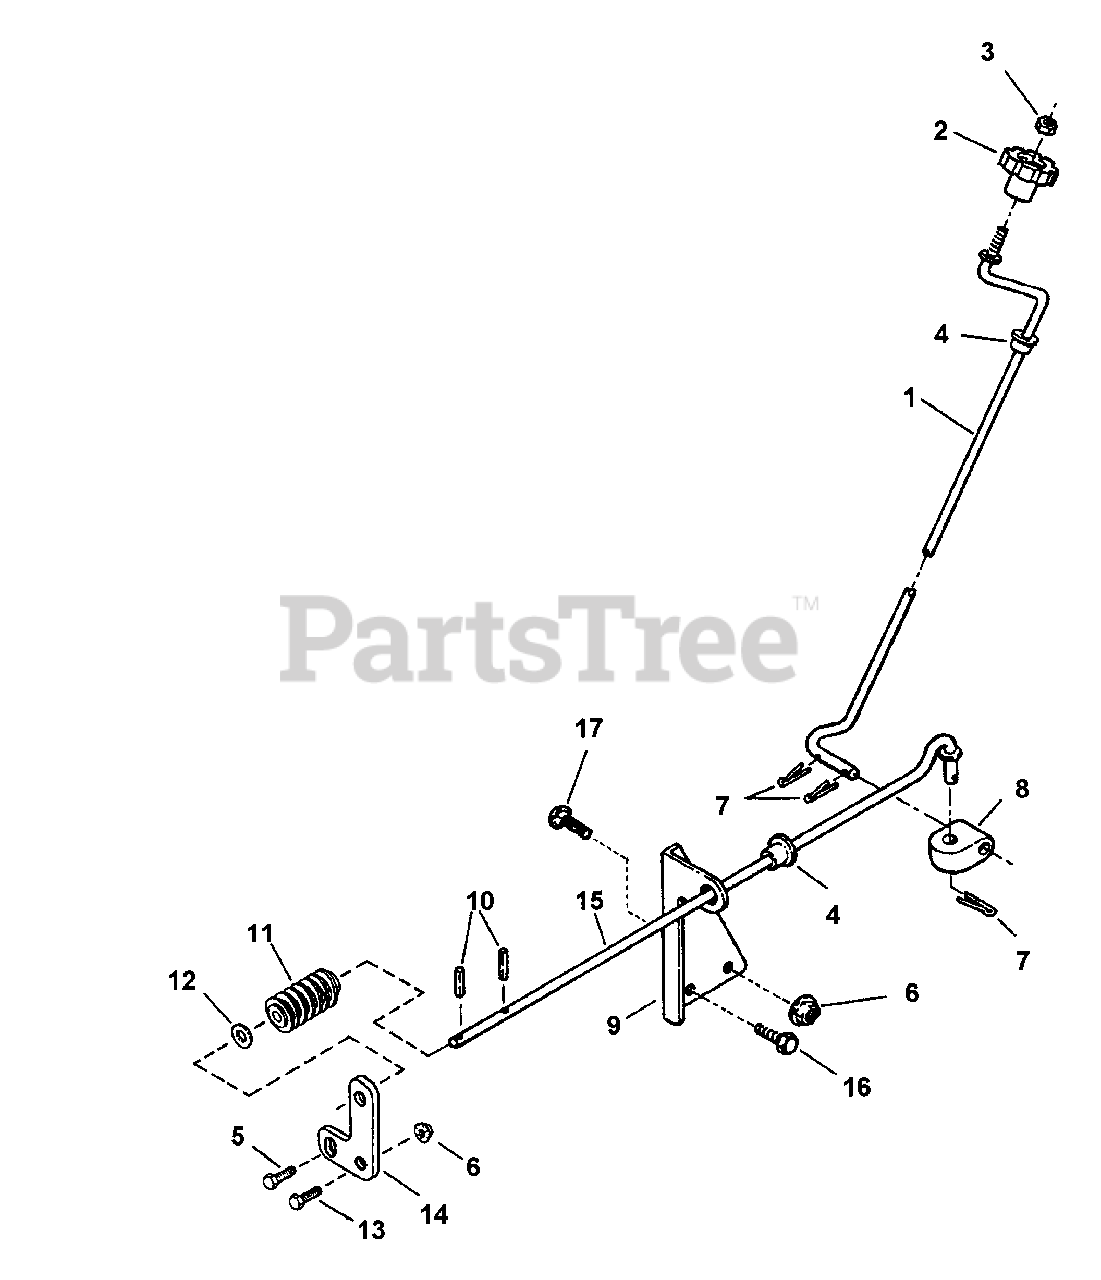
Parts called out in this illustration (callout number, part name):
1	CRANK, Chute
2	KNOB, Chute Crank
3	NUT, 5/16-18 Hex Center Lock, Grade B
4	BUSHING
5	SCREW, 1/4-20 x 1/2" Hex Washer Self-Tapping
6	NUT, 5/16-18 Hex Flange Lock, Grade 5
7	PIN, 3/32 x 3/4" Cotter
9	BRACKET, Shaft
10	PIN, 1/8 x 3/4" Roll
11	WORM
12	WASHER, Spring
13	SCREW, 5/16-18 x 5/8" Hex Head Cap, Grade 5
14	BRACKET, Worm Shaft
15A	SHAFT, Worm
15B	SHAFT, Worm (long)
16	SCREW, 5/16-18 1/2" Hex Washer Self-Tapping
17	BOLT, 5/16-18 x 5/8" Short Neck Carriage, Grade 5
